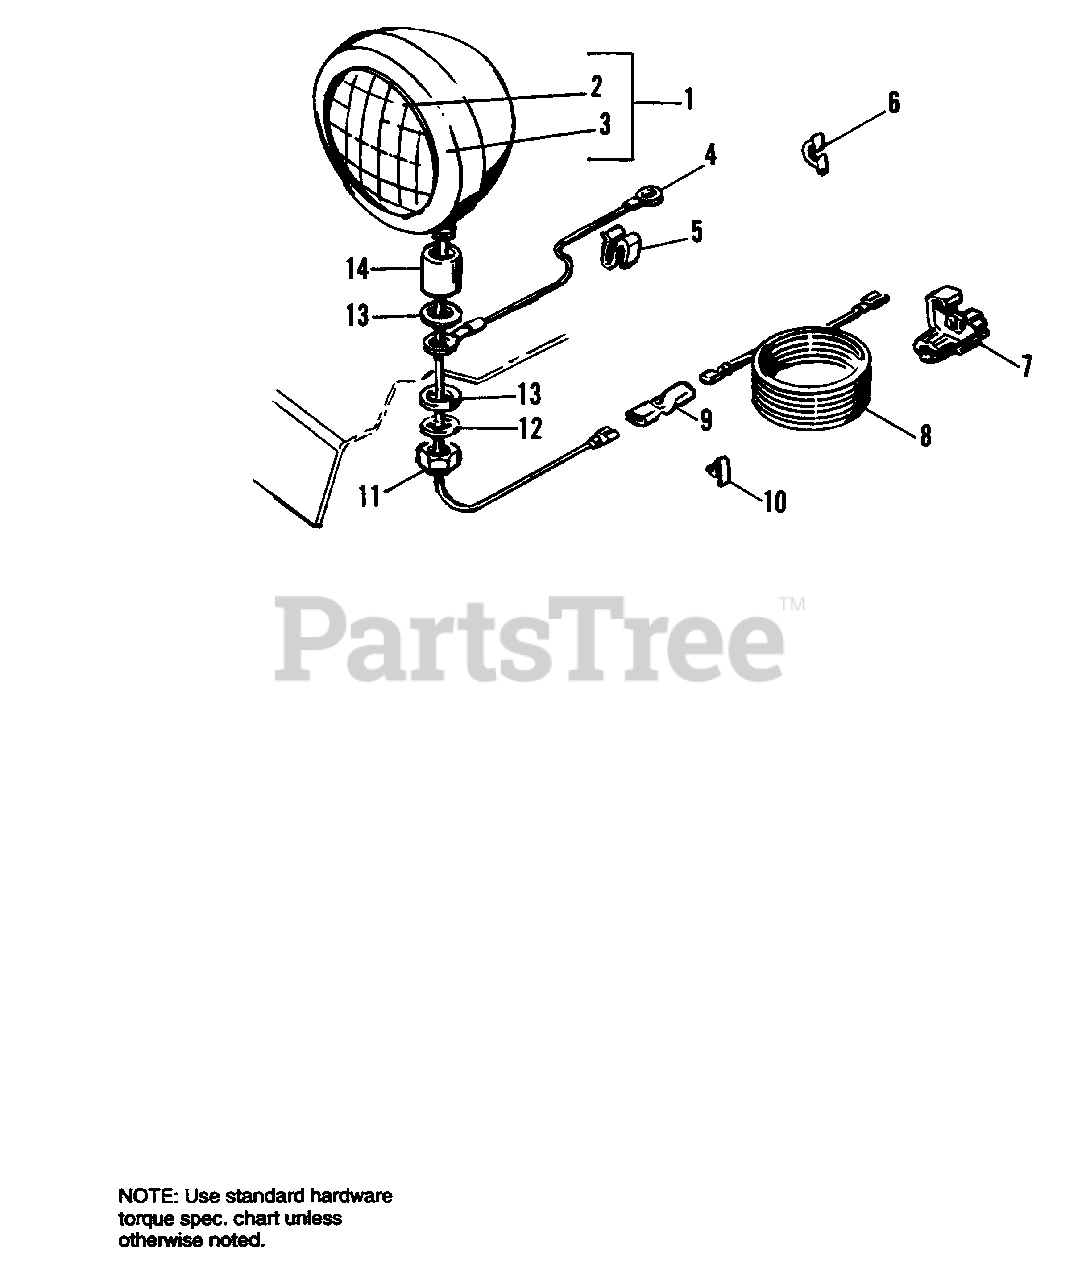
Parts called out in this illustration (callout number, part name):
1	LAMP ASSY.
2	LAMP, Seal Beam
4	WIRE, Rear Light Ground
6	CLIP, Wire
9	CONNECTOR
10	CLIP, Wire
11	NUT, Hex, 1/2-13, Unc 2B, Steel
12	LOCKWASHER, Spring, 1/2, Pltd.
13	WASHER, Plain, 7/16
